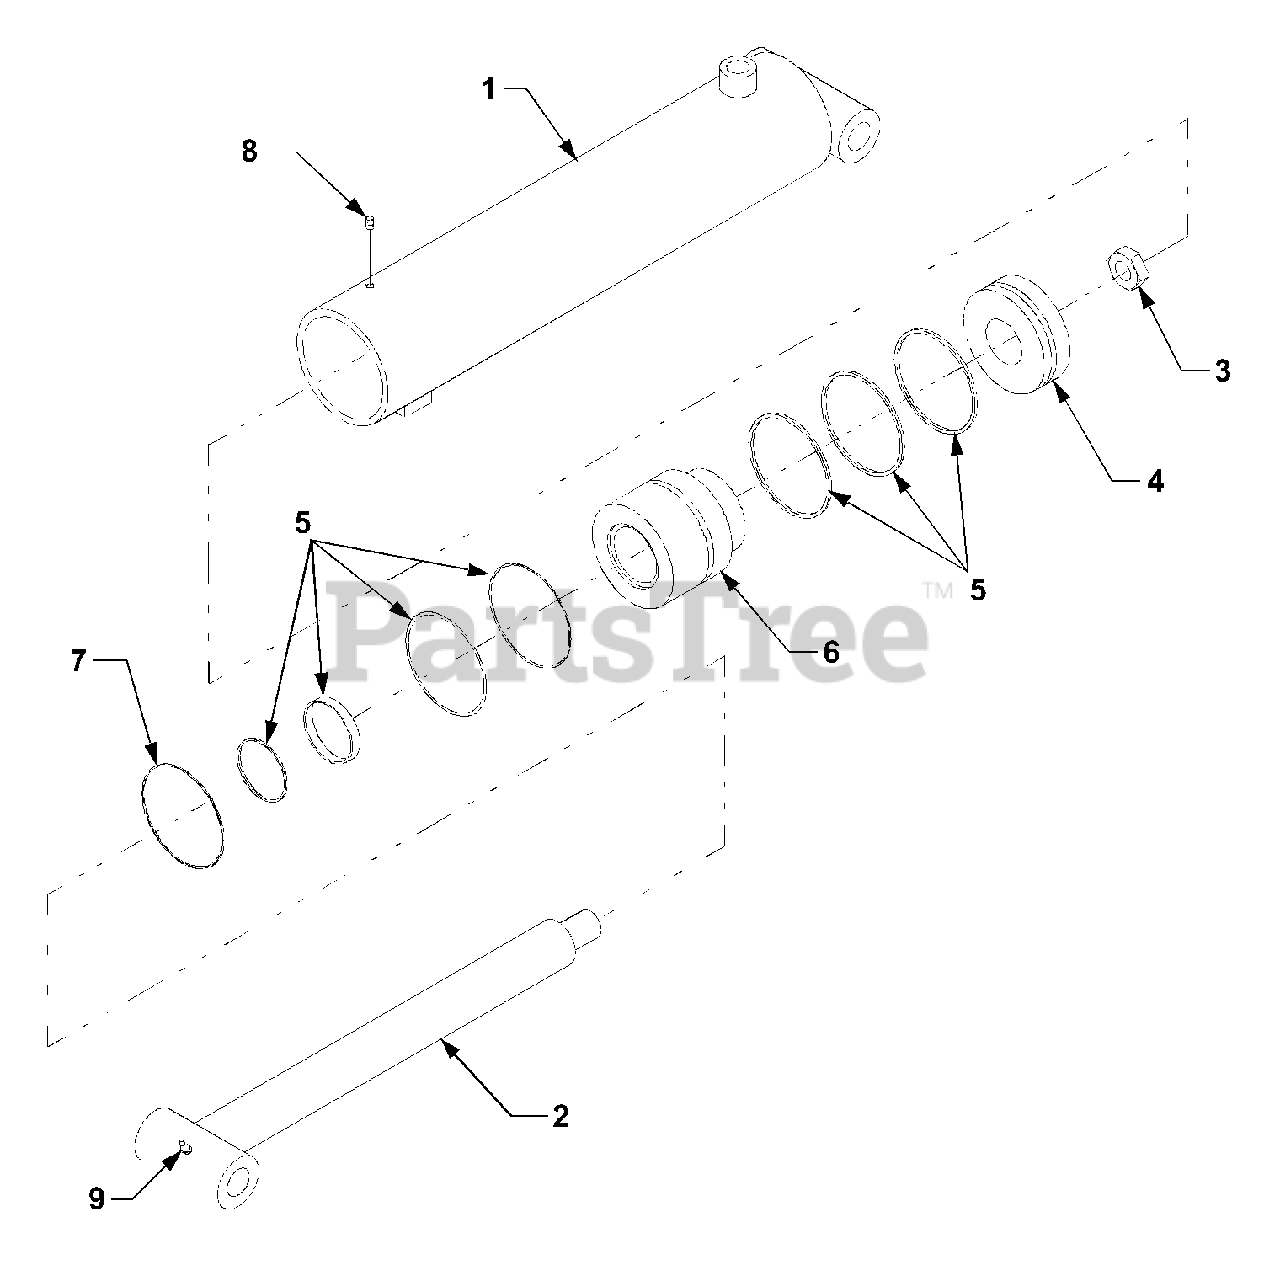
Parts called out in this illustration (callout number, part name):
1	Tube Assembly
2	Rod Assembly
7	Retaining Ring
9	Grease Fitting
